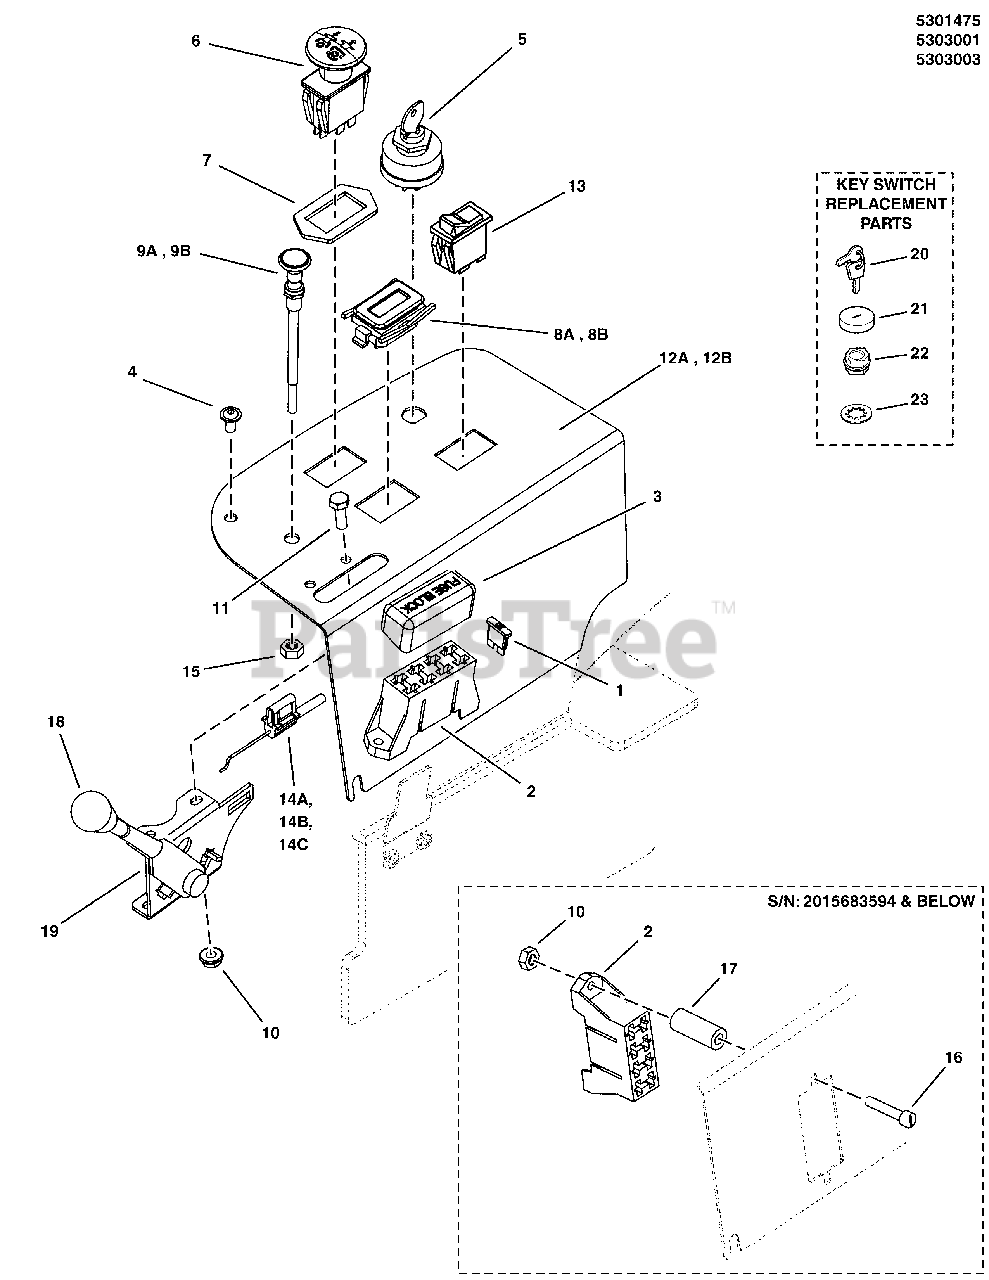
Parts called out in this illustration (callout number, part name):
1	FUSE, ATO-20 (20 AMP)(SV)
2	FUSE, BLOCK (SV)
3	COVER, VINYL, FUSE BLOCK
4	SCREW, ALLEN HEAD 1/4-20X.500 ZINC PHOS
5	SWITCH ASSEMBLY, Ignition Indak No Keys/Hdwr
6	SWITCH, BLADE ENGAGEMENT
7	RING, SWITCH RETAINER
10	NUT, Nylock, #10-24, GR2
11	SCREW, #10-24 X 3/4" ROUND PHILLIPS
13	SWITCH, HEADLIGHT
15	NUT, 3/8-24 HEX (SV)
16	SCREW, #10-24 X 2" ROUND PHILLIPS
17	SPACER, .20 X .38 X 1.25
18	THROTTLE CONTROL HANDLE/KNOB
19	LEVER, THROTTLE CONTROL
20	KEYS, Blister Pk (KIDS+MWRS DON'T MIX) English/Spanish (set of two, one coated)
21	COVER, For Ignition Switch, Plastic
22	NUT, 5/8-32 Hex Flange (Ignition Switch Die Cast)
23	LOCKWASHER-INTERNAL TOOTH, .625 THIN BLK (SV)
